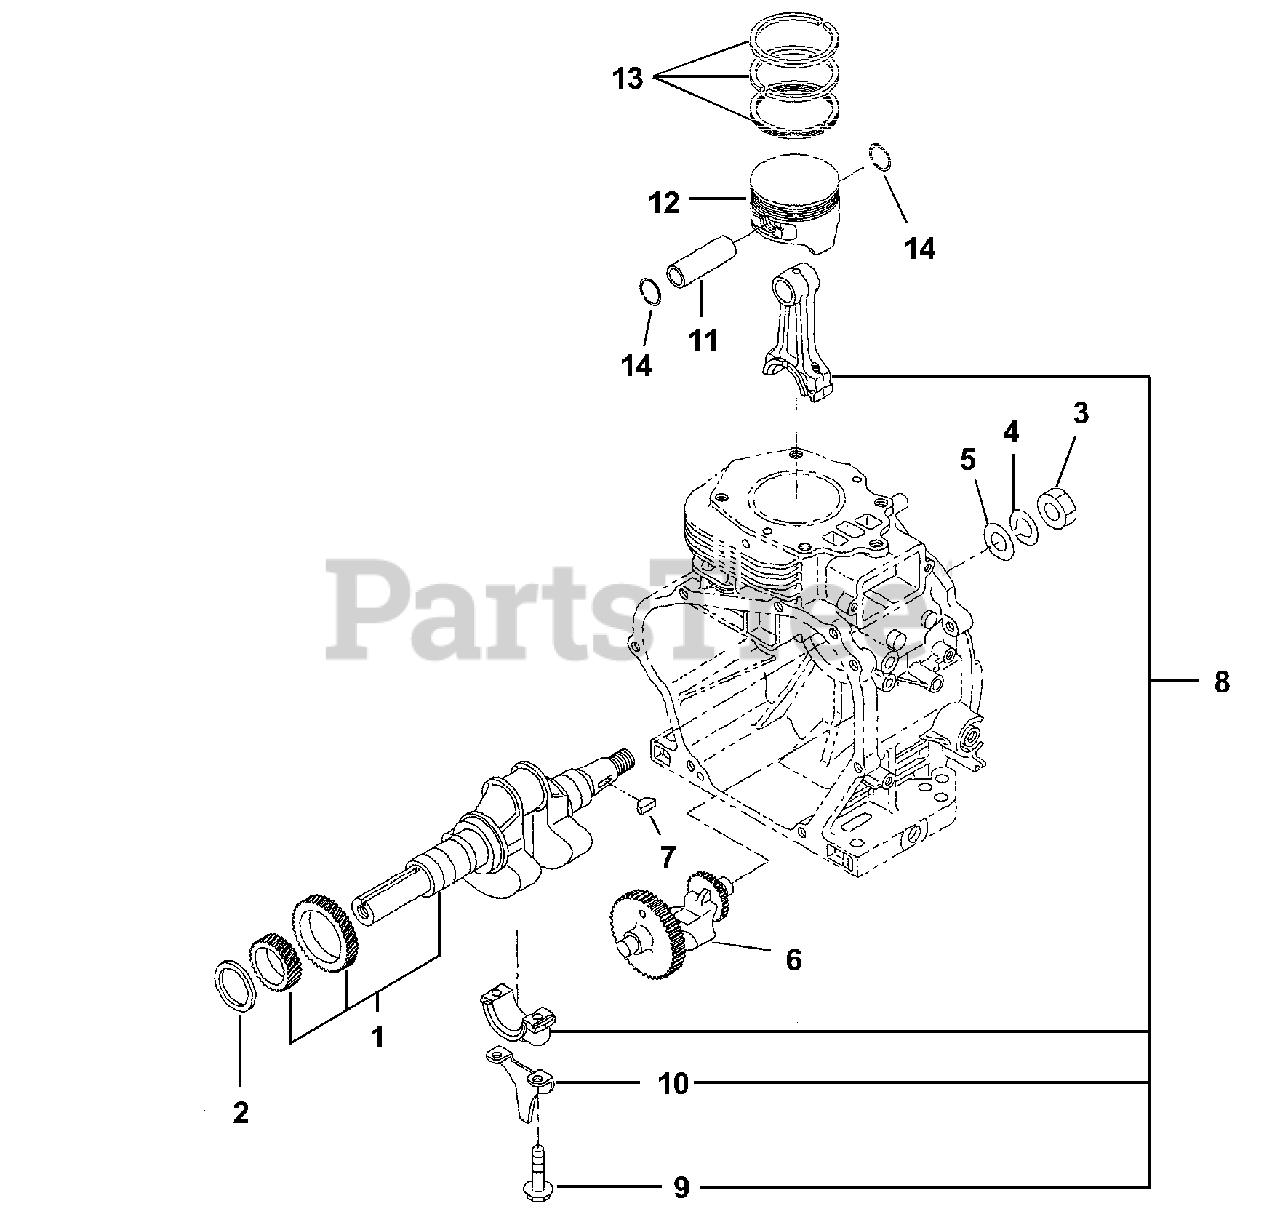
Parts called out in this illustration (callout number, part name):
1	Crankshaft cp
2	Spacer (.6)
3	Nut
4	Spring washer
5	Washer
6	Balancer shaft
7	Woodruff key
8	Connecting rod Ay
9	Connecting rod bolt
10	Oil scrapper
11	Piston pin
12	Piston
13	Piston ring set (std)
14	Clip
